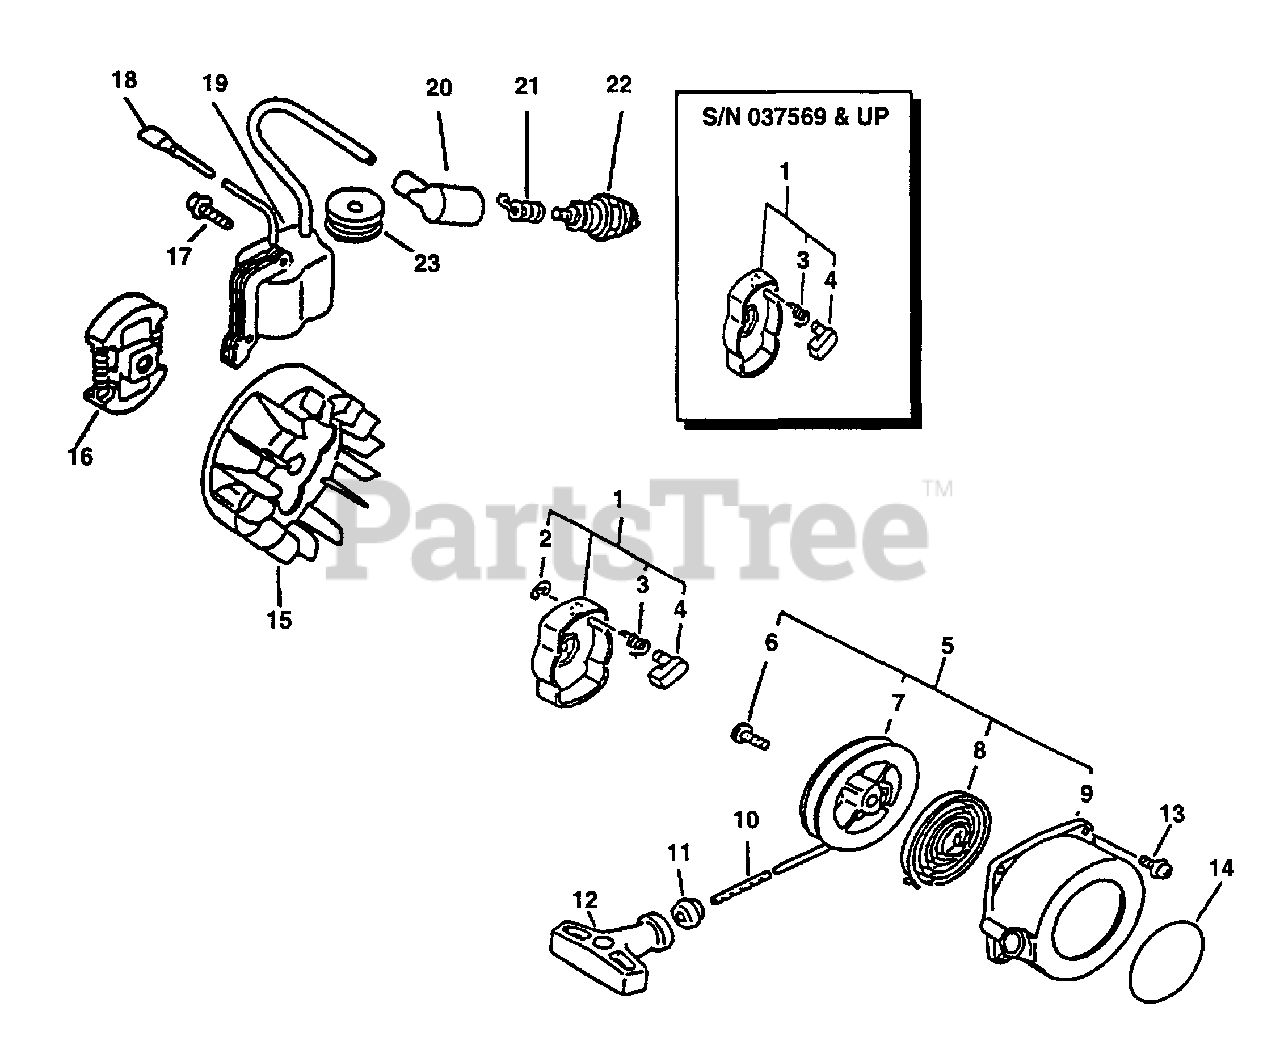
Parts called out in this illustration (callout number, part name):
1	STARTER PAWL ASSY
2	RING, RETAINING - 4
3	SPRING, RETURN
4	PAWL, STARTER
4	PAWL, STARTER - BLACK
5	STARTER ASSY
7	REEL, ROPE
8	SPRING, REWIND
9	CASE, STARTER
10	ROPE, STARTER - 3X890
11	GUIDE, ROPE
12	GRIP, STARTER
13	SCREW - 4X16
14	LABEL - ECHO
15	FLYWHEEL
16	CLUTCH ASSY
17	SCREW - 4X22
18	LEAD - GROUND
19	COIL, IGNITION
20	CAP, SPARK PLUG
21	TERMINAL, SPARK PLUG CAP
22	SPARK PLUG -- BPM-7A
23	GROMMET
